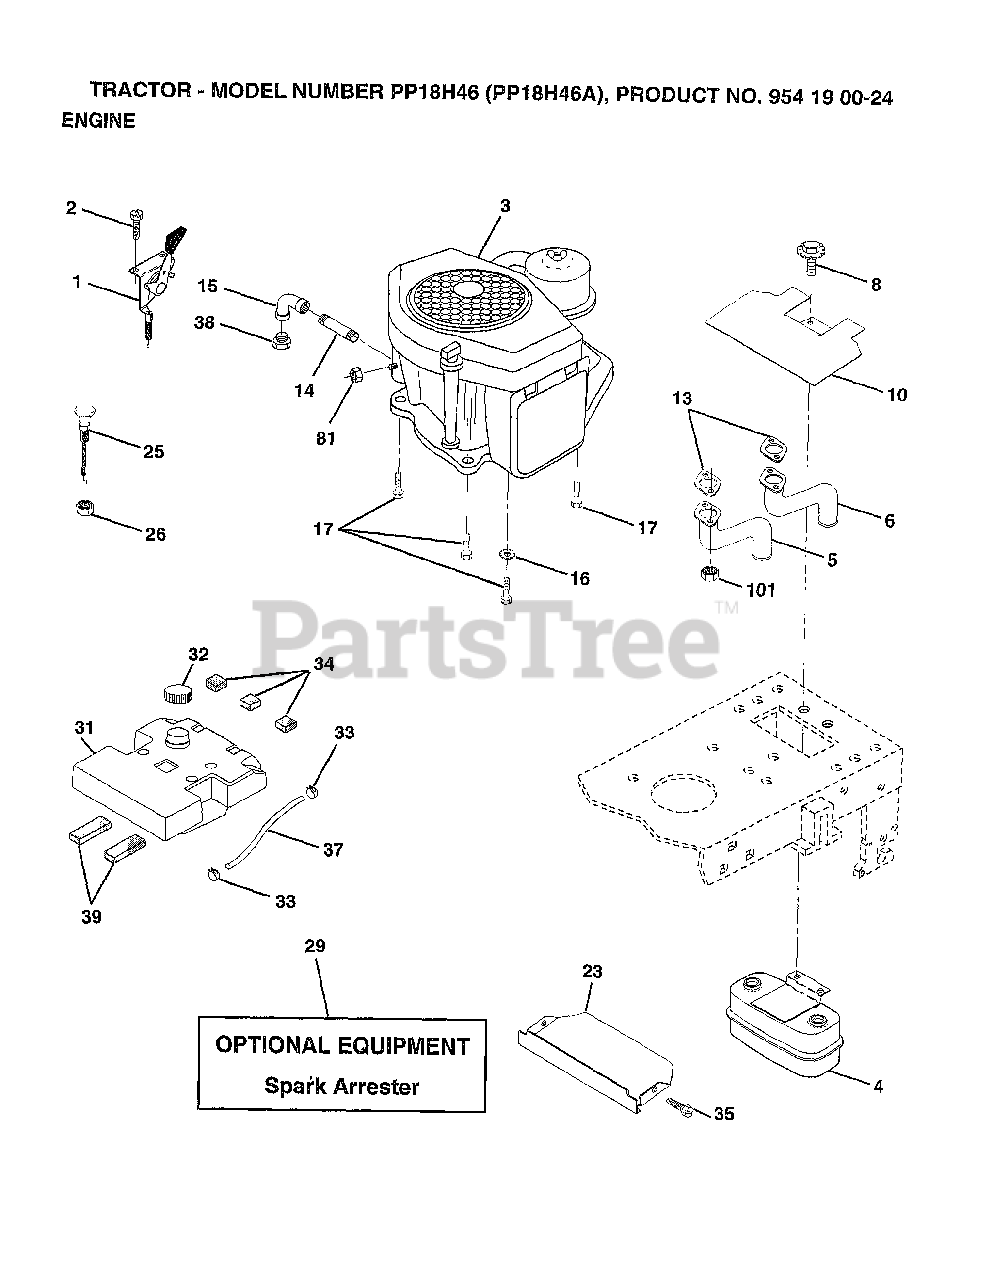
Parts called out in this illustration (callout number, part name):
2	SCREW LT
4	MUFFLER.TW.LOTONE
5	PIPE-EXHAUST.LH
6	PIPE-EXHAUST.RH.
7	CLIP T
8	BOLT.5/16-18.UNC
10	SHIELD.HEAT.MUFF.
13	GASKET
14	PIPE NIPPLE LT
15	ELBOW
16	LOCKWASHER
17	SCREW LT
23	SHIELD.BRN/DBR.GD
25	CONTROL.CHOKE.37
26	"NUT,KEPS 3/8-24IM"
31	"TANK.FUEL,3.5 GAL"
32	CAP ASM FUEL
33	HOSE CLAMP
34	PAD-SPACER LT
35	SCREW
37	FUEL LINE T
39	PAD IDLER TI
81	NUT
101	NUT FLANGE M8-125
